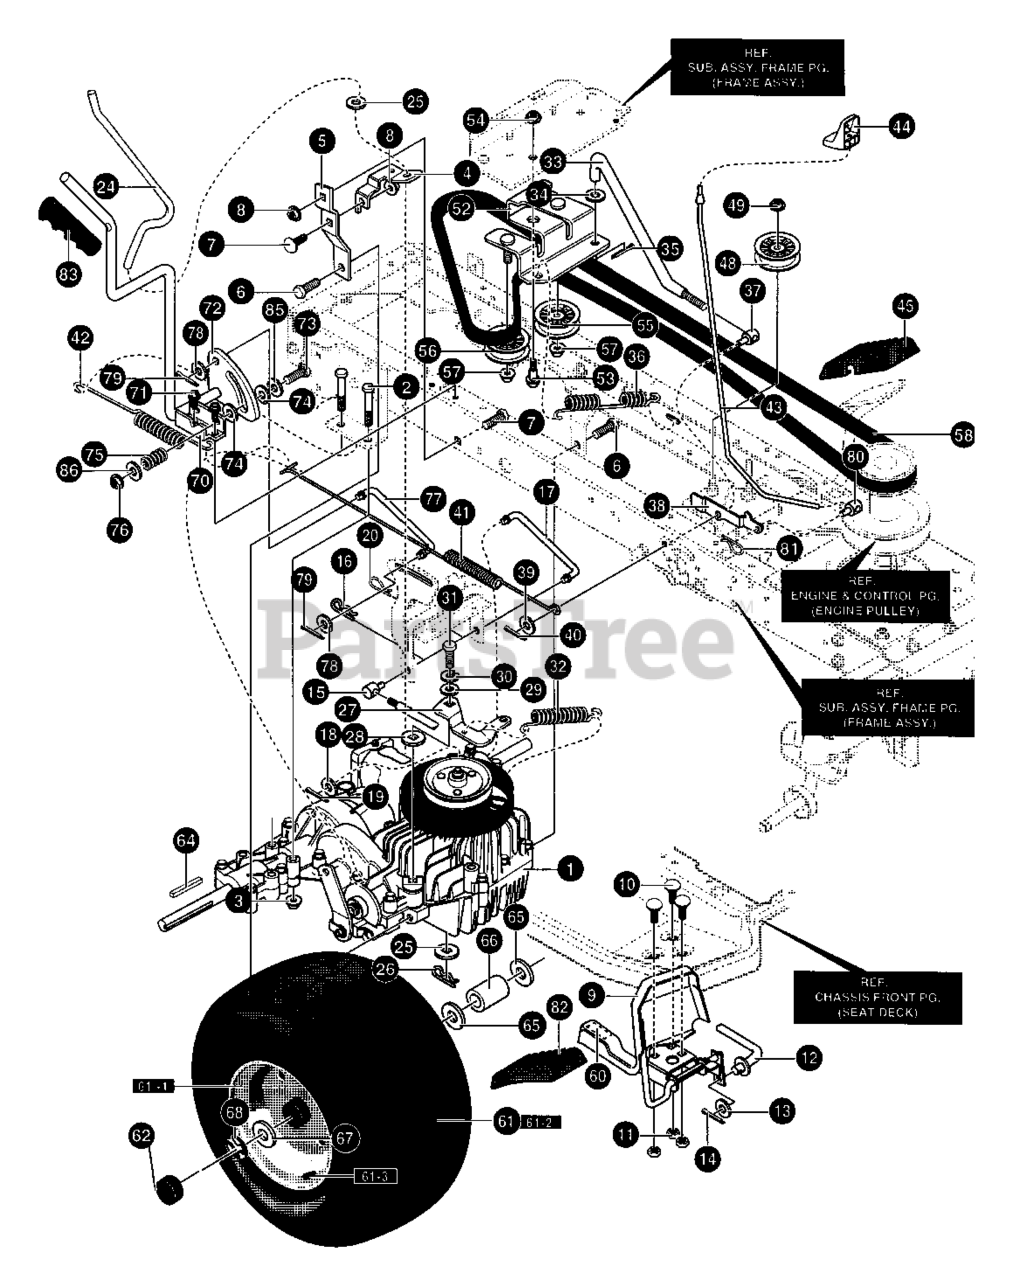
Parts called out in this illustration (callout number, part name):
1	Transaxle, Peerless **
2	SCREW, 5/16-18 x 2.50
3	NUT, 5/16-18
4	BRACKET, DISCONNECT
5	TORQUE STRAP
6	SCREW, 5/16-18 x 0.75
7	BOLT, 5/16-18X.63
8	NUT, 5/16-18
9	ASSEMBLY, PEDAL
10	BOLT, 5/16-18X.75
11	NUT, 5/16-18
12	ROD, PEDAL LINK
13	HAIRPIN
15	NUT, Adjusting, 1/2-13
16	PIN, HAIR
17	ROD HYDRO LINK
18	WASHER, FLAT
19	PIN, COTTER
20	PIN, HAIR
24	ROD HYRO LINK
25	Washer
26	PIN, COTTER
27	ARM DISCONNECT
29	WASHER, FLAT
31	SCREW 1/4-28X.75
32	SPRING, EXTENSION
33	ROD, CLUTCH
34	Washer
35	PIN, COTTER
36	SPRING, CLUTCH
37	NUT, ADJUSTING
38	LATCH, PARK BRAKE
39	WASHER, FLAT
40	PIN, COTTER
41	SPRING, EXTENSION
42	SPRING, TENSION
43	ROD, PARKING BRAKE
44	KNOB, PARKING BRAKE
45	PAD, CLUTCH/BRAKE
48	PULLEY, IDLER
49	NUT, 3/8-16
52	BRACKET IDLER
53	BOLT 3/8-16
54	NUT, 3/8-16
55	PULLEY, IDLER
56	PULLEY, V-IDLER
57	NUT, 3/8-16
58	MOTION DRIVE
60	PAD, TOE
61	TIRE & RIM 20X10-8
61-1	VALVE STEM
61-2	RIM, CARL
61-3	TIRE 23X9.5
62	HUB CAP
64	KEY, SQUARE
65	WASHER, FLAT
66	SPACER
67	WASHER, FLAT
68	RING, RETEX
70	BRACKET, HAND CONTROL
72	LEVER HAND CRUISE
73	BOLT 5/16-18X.5
74	WASHER, FRICTION
75	SPRING - COMP
76	NUT, 5/16-18
77	LINK, CRUISE CONTROL
78	Washer
79	PIN, COTTER
80	CLEVIS, PARKING BRAKE
81	PIN, COTTER
82	PAD, SPEED CONTROL PEDAL
85	WASHER, FLAT
86	WASHER, FLAT
